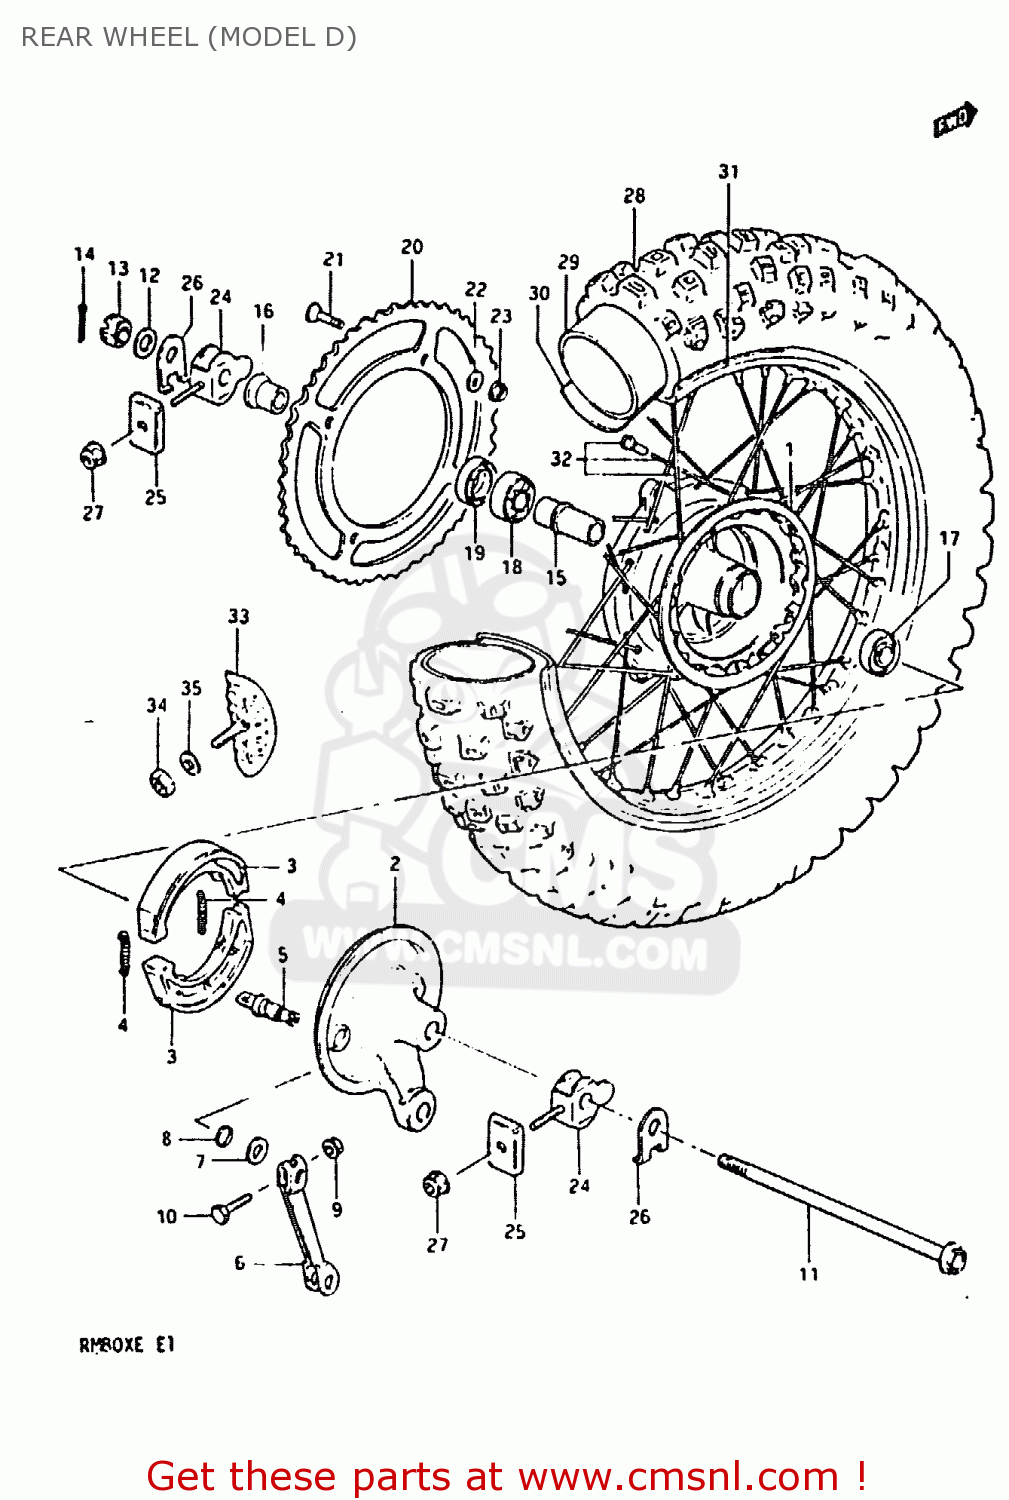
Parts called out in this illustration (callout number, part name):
1	HUB,REAR
2	PANEL,REAR HUB
3	SHOE,BRAKE
4	SPRING(L:35.8)
5	CAM,BRAKE
6	LEVER,RR BRAKE CAM
7	WASHER(12.5X20X1)
8	O RING(D:2.5,ID:11.4)
9	NUT
10	BOLT
11	AXLE,REAR
12	WASHER
13	NUT 12MM
14	PIN 30X20
15	SPACER,REAR HUB BEARING
16	SPACER,RR AXLE,L
17	BEARING, RH
18	BEARING
19	OIL SEAL(17X38X5)
20	SPROCKET,REAR
21	SCREW(8X33.5)
22	WASHER
23	NUT
24	ADJUSTER CHAIN
25	ADJUSTER,CHAIN
26	WASHER,CHAIN ADJUSTER
27	NUT
28	TIRE
29	TUBE ASSEMBLY,WHEEL,INNER
30	PROTECTOR,INNER TUBE
31	RIM,REAR WHEEL
32	SPOKE SET
33	STOPPER,BEAD
34	NUT
35	WASHER
